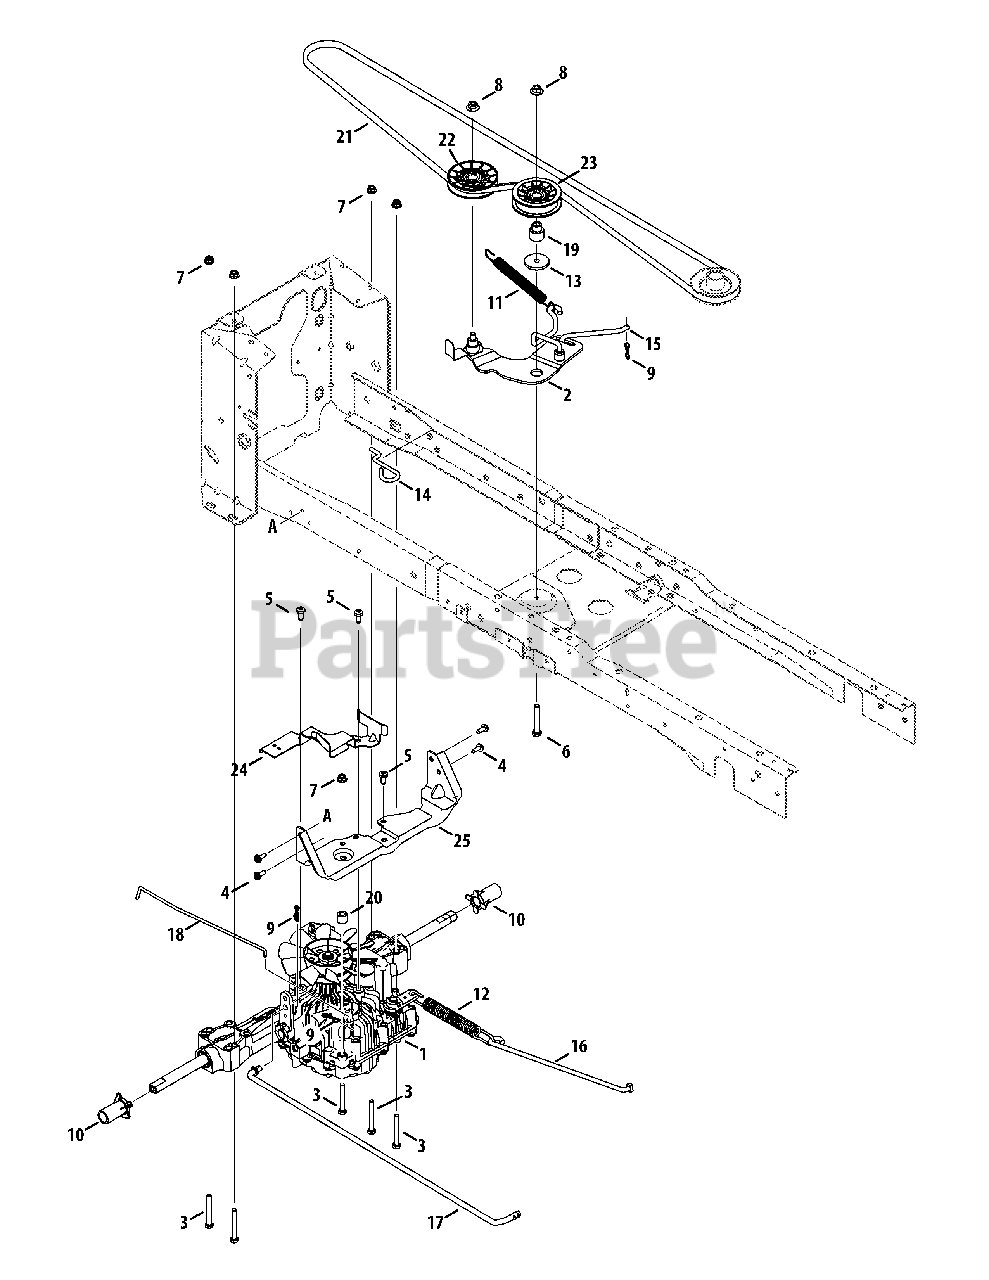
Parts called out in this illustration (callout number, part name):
1	Transmission, Tuff Torq K46
2	Idler bracket Assembly
3	Hex Screw, 5/16-18, 2.50, Gr5, Std
4	Screw, M6-1 x .625
5	Screw, Self-tapping, 5/16-18, 0.750
6	Hex Screw, 3/8-16, 2.25, Gr5
7	Nut, Flange Lock, 5/16-18, Nylon
8	Flange Lock Nut, 3/8-16
9	Pin, Cotter, Bow-Tie 72
10	Sleeve, .765 Id x 2.11
11	Spring, Extension, .700 Dia x 8.41
12	Spring, Extension, .90 Dia x 8.14
13	Shoulder Spacer, .884 x .190
14	Deck Spring Rod
15	Idler Link
16	Rod, Brake, Tuff Torq
17	Rod, Control, Tuff Torq
18	Rod, Transmission, Bypass
19	Shoulder Spacer
20	Spacer, .34 x .75 x .63
21	Belt, V-Type
22	Idler Pulley, 3.56 OD
23	Idler Pulley, 3.00 OD
24	Belt Keeper Bracket
25	Transmission Bracket
